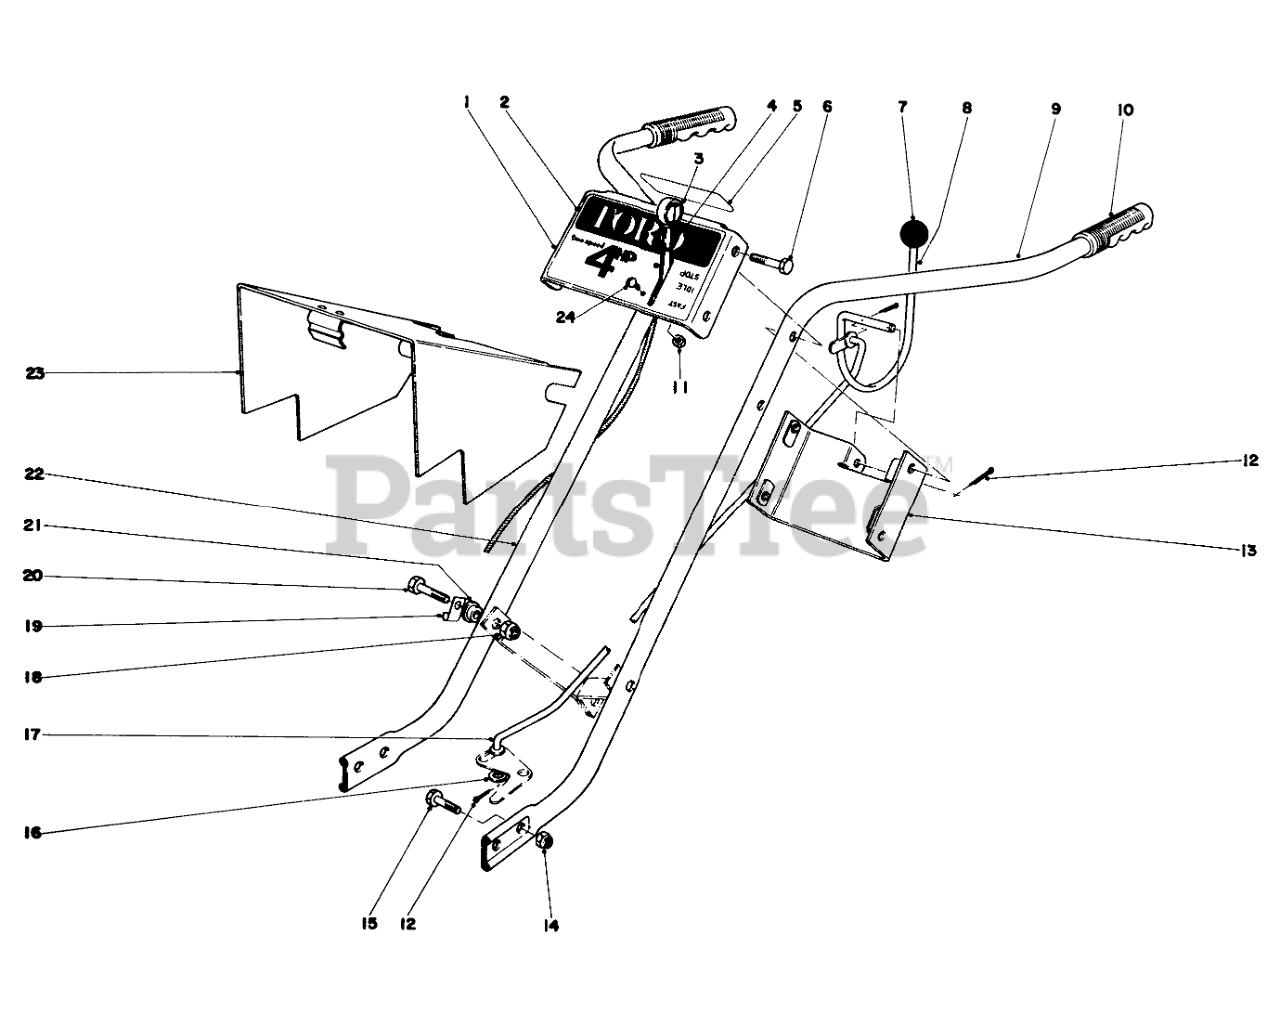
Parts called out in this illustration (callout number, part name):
1	Control Plate
2	Decal
4	Throttle Control
5	Decal Clutch
6	SCREW-HH
7	KNOB-CONTROL
8	Clutch Control
9	Handle L.H.
10	Handle Grip
11	NUT-KEPS
12	PIN-COTTER
13	Handle Brace
14	NUT-LOCK, CONE
15	SCREW-HH
16	WASHER-FLAT
17	Clutch Rod
18	NUT-LOCK, CONE
20	SCREW-HH
21	Spacer
22	Handle R.H.
23	Pulley Cover
24	SCREW-PPH
